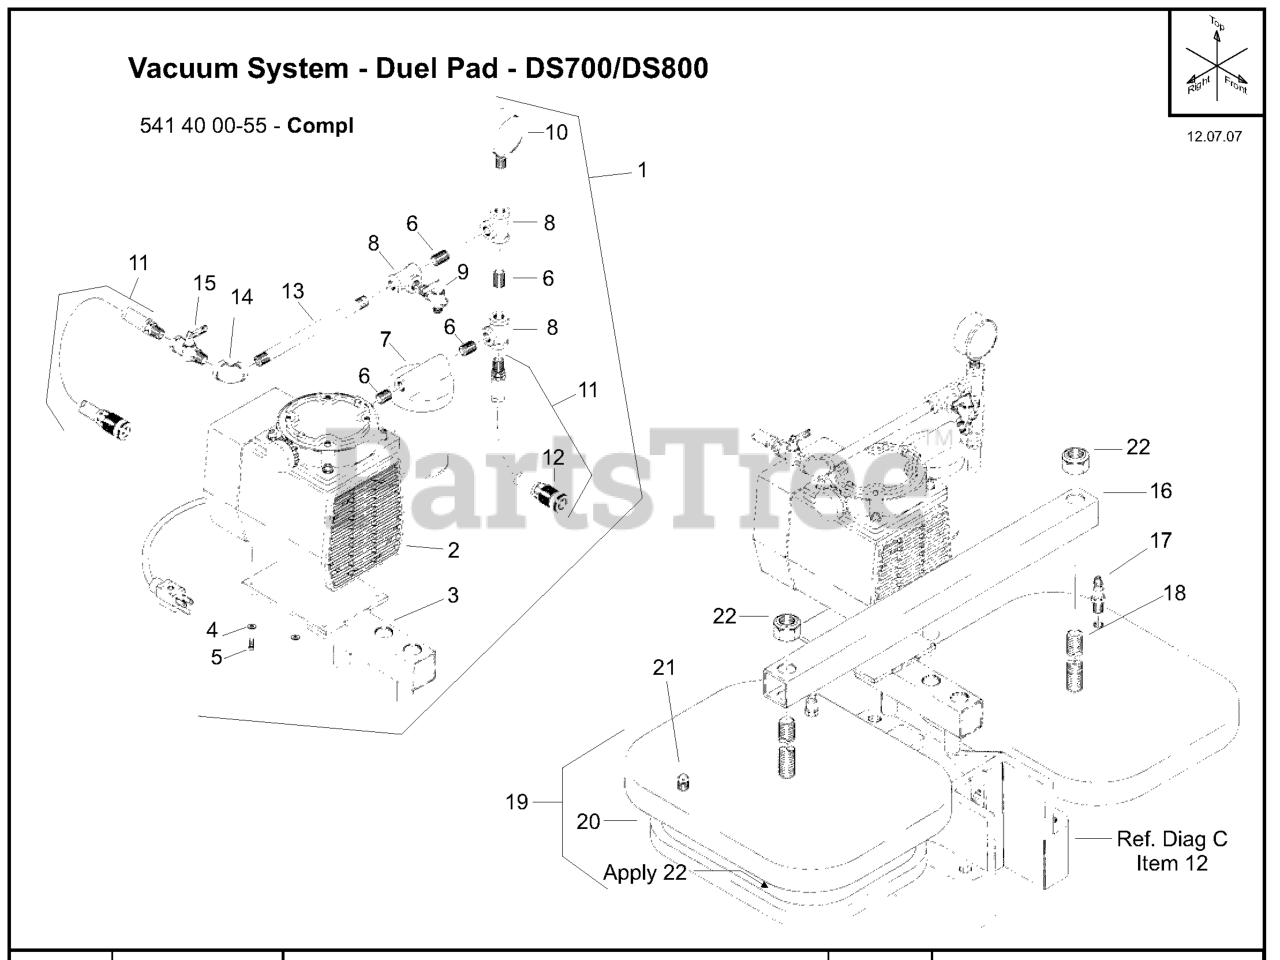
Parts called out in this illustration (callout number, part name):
1	Vacuum Pump Assy
2	Pump, Vacuum
3	Frame - Vacuum Pump
4	Washer, Flat 1/4 SAE
5	Capscrew, Soc Hd 10-32 x 1/2
6	Pipe Fit., Nipple 1/4 NPT x Close - Galv
7	Trap, Water
8	Pipe Fit., Female Tee 1/4 NPT - Galv
9	Valve, Release 1/4 NPT
10	Gauge, Vacuum
11	Hose Assy
12	Body, Quick Disconnect, 1/4 PL
13	Pipe Fit., Nipple 1/4 x 7 Galv
14	Pipe Fit., 90 Deg Fem Elbow 1/4 NPT - Galv
15	Valve Shut-Off - Single Pad
16	Bar, Cross - Duel Pad
17	Stem, Quick Disconnect
18	Stud, Pad 3/4-10 x 8"
19	Pad, Vacuum
20	Gasket, Rubber
21	Pipe Fit., Plug 1/4 NPT
22	Nut, Hex 3/4-10
23	Adhesive, Tube - 5 OZ
